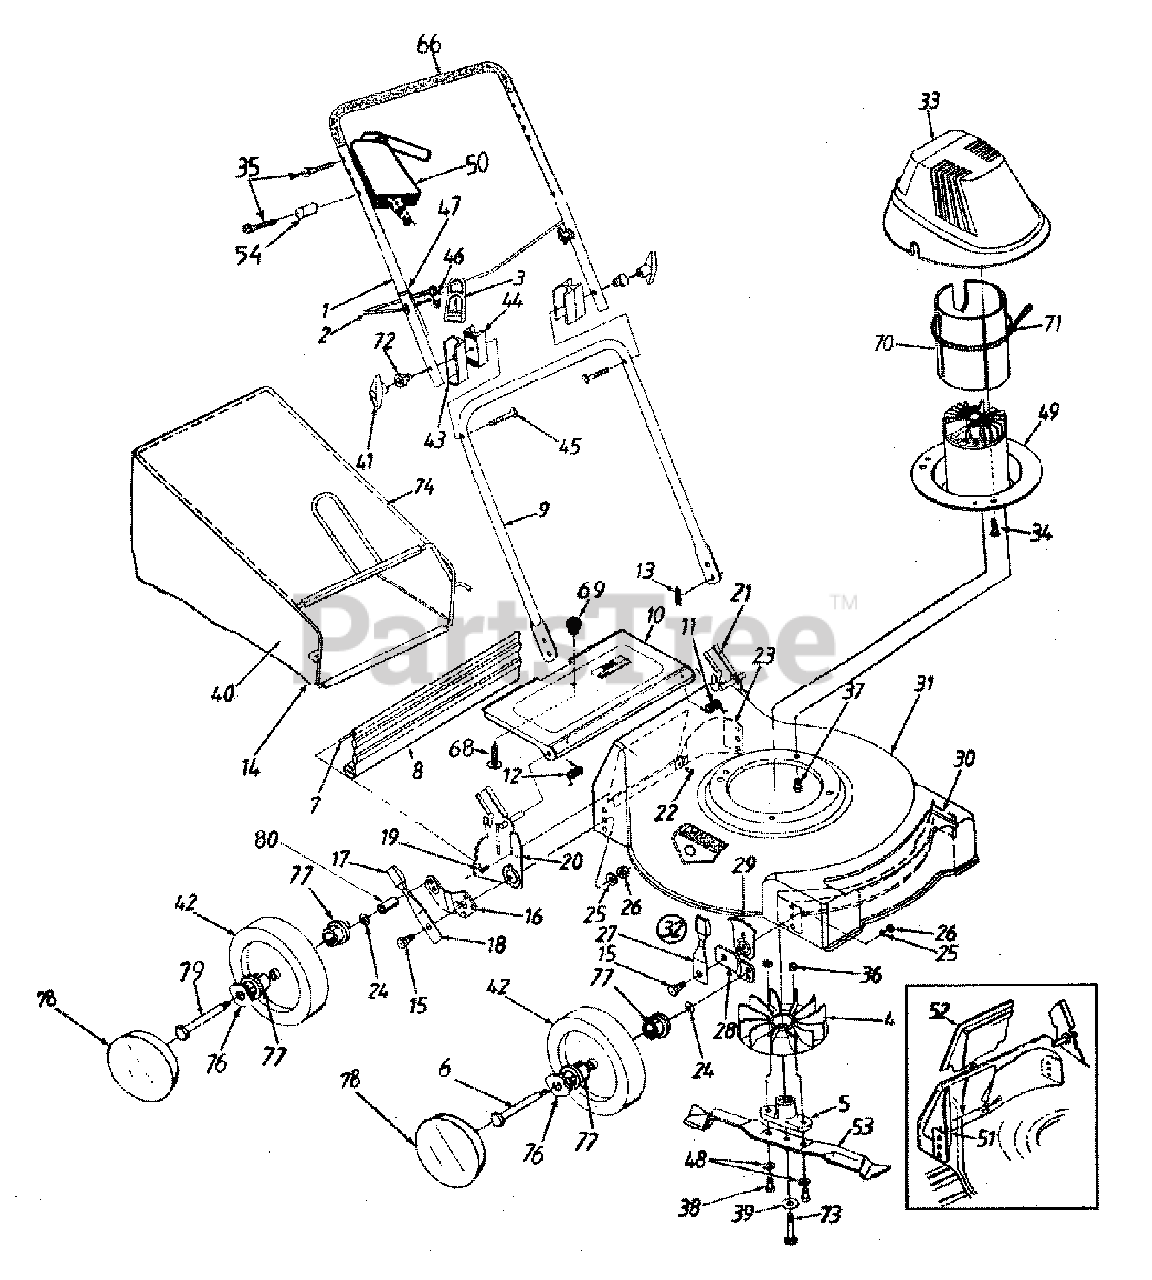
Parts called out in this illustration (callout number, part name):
3	Strain-Relief Cord
5	Blade Adapter
7	Rear Flap Wire
12	Door Spring (R. H.)
13	Hairpin Clip
16	Pivot Bar (R.H.)
17	Spring Lever Knob
19	Hex AB-Tap Scr.
20	Handle Bracket Ass'y. (R.H.)
21	Handle Bracket Ass'y. (L.H.)
22	Torx . Mach. AB-Tap Scr.
25	Bell Washer .39" I.D. x 1.38" o.d.
26	Hex Nut 3/8-16 Thd.
27	Spring Lever Ass'y. w/Knob
29	Height Adj. Plate
34	Scr. #10-24 x .75" Lg.
35	C-Sunk Scr.1/4-20 x 1.8" Lg.
36	Hex Nut 3/8-24 Thd.
37	Hex Tt-Tap Scr. 3/8-16 x 1" Lg.
38	Hex Bolt 3/8-24 x 1.25" Lg.
39	Bell Washer .396" I.d. x 1.14"
40	Grass Bag w/o Icon
41	Plastic Knob
42	Wheel Ass'y. Comp.
43	Upper Handle Insulator
44	Lower Handle Insulator
45	Carriage Bolt 5/16-18 x 3 Lg.
47	Cable Tie
48	Bell Washer 3/8" I.d.
49	Motor, Cord & Switch Ass'y.
50	Cord & Switch Ass'y. Comp.
53	19" Mulching Blade
54	Spacer
66	Foam Grip
68	Truss Scr. #10-24 x .38" Lg.
70	Cable Tie
71	Insulator Motor Hsg.
72	Insulator Knob
73	Hex Bolt 3/8-24 x 2.5"
77	Ball Bearing
78	Hub Cap
79	Rear Axle Bolt
80	Spacer
